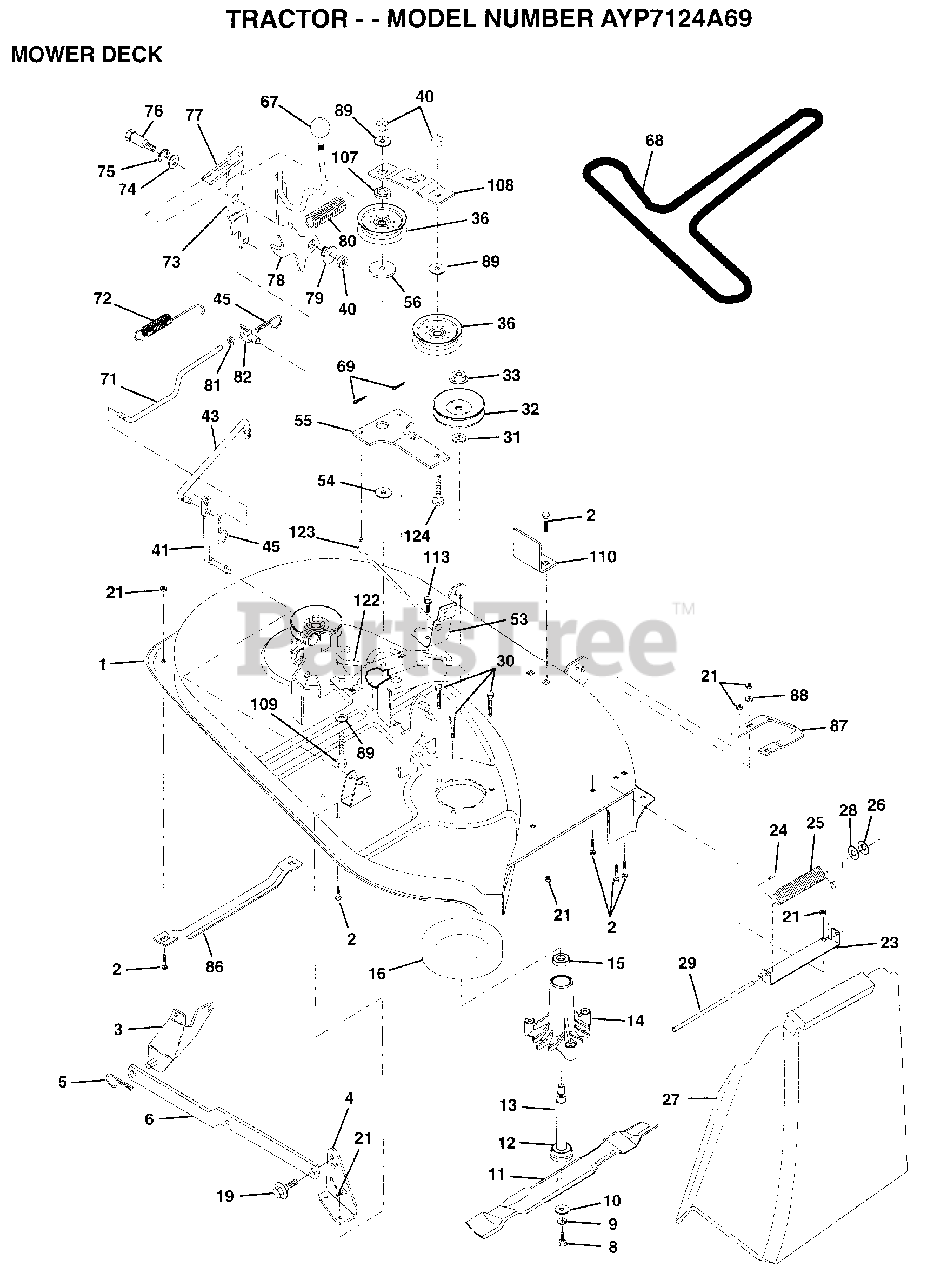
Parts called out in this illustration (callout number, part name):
2	BOLT
3	BRKT ASM SWAY BAR
4	BRKT DECK SW BAR
8	BLADE BOLT
10	WASHER.HARD.BLADE
11	"BLADE.38""V.MULCH"
12	BEARING.BALL
14	HSG ASM MANDREL
15	BEARING
16	STRIPPER RND MWR
19	BOLT SHD 5/16-18
23	BRKT DEFLECTOR
24	CAP-SLEEVE LT
25	SPRING TORSION
26	NUT PUSH M
27	DEFLECTOR-SHLD T
28	WASHER
29	ROD-HINGE T
31	WASHER
36	FLAT IDLER PULLEY
41	PIVOT ROD
43	CLUTCH ROD SECOND
45	RETAINER M
53	BRAKE ASM
54	HARDENED WASHER
55	IDLER ARM ASSY
56	SPACER RETAINER
67	KNOB T(3/8 HOLE)
68	BELT.V.T-PATH
71	ROD CLUTCH 38/42
72	RETURN SPRING
73	CLUTCH ARM SECOND
74	WASHER
75	RING
76	SHOULDER BOLT
77	SPRING KEEPER
79	BUSHING
81	NUT
82	TRUNION ADJ
86	RUNNER-LH M
87	RUNNER RH
88	WASHER M
89	WASHER GT
92	NUT
107	RETAINER SPACER
108	IDLER ARM STIFF
109	BOLT
110	UPSTOP DECK FT 38
113	SCREW
122	BRAKE ROD LH
123	BRAKE ROD RH
124	BOLT
